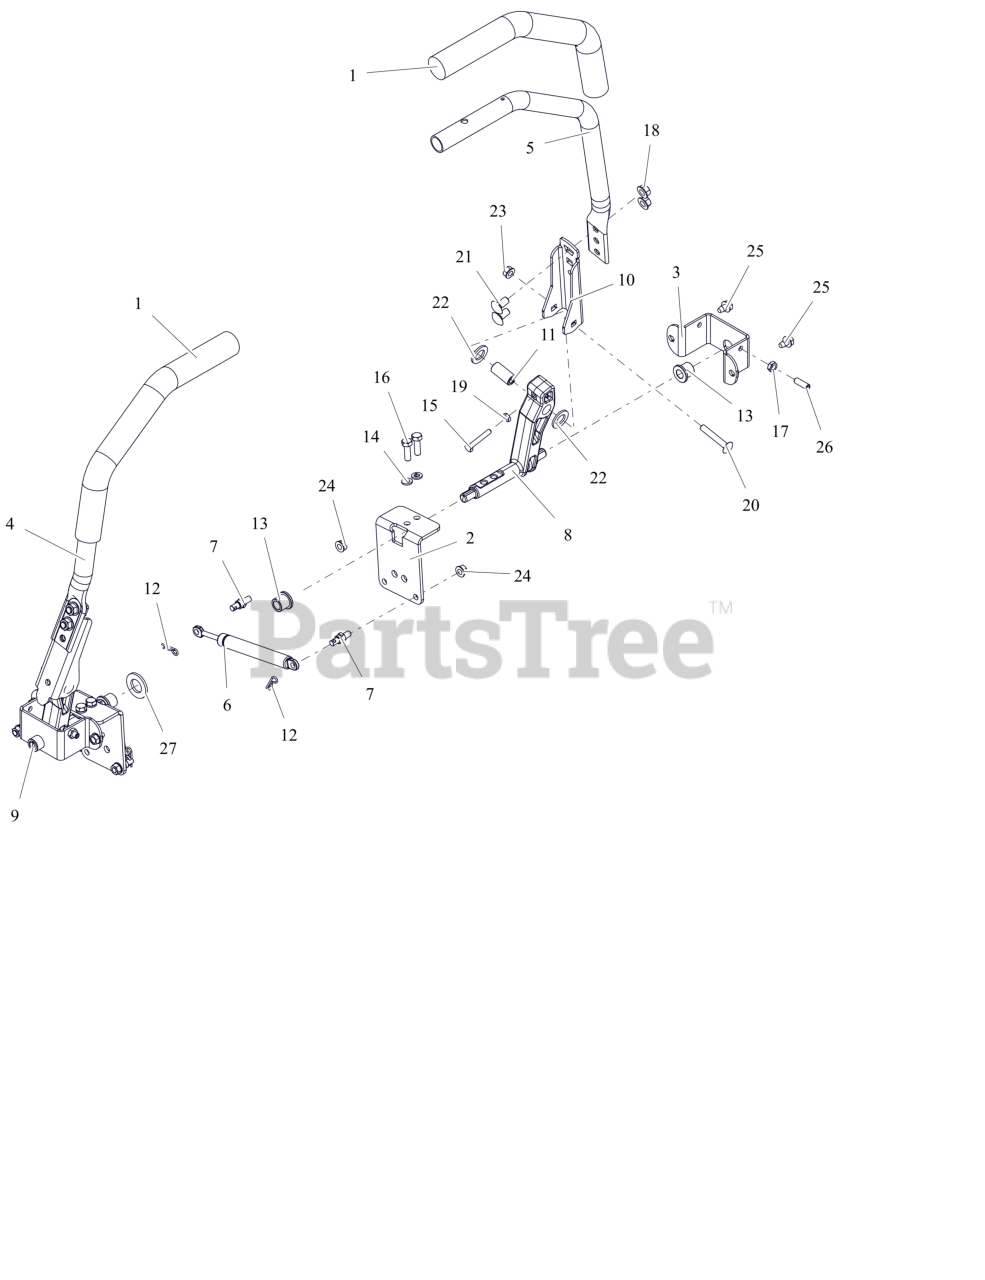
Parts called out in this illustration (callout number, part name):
1	GRIP, HANDLEBAR
2	BRKT, STEEERING
3	BRKT, STEERING
4	HANDLE- STEERING-RH
5	HANDLE- STEERING-LH
6	DAMPER, STRAIGHT MOUNT
7	COUPLER, DAMPER MOUNT
8	ARM- STEERING-LH LOWER (MACH)
9	ARM- STEERING-RH LOWER (MACH)
10	ARM- CONTROL UPPER
11	BSHG-SLV .342 X .627 X 1.331
12	PIN, HAIR #213 .08X1.19 ZCC
13	BHSG-FLG .500X.750X.750X.125
14	WSHR,LK-REG .312X.078 ZCC
15	BLT, HEX .25-20X1.50F G5 ZCC
16	BLT, HEX .31-18X1.00 G8 ZCC
17	NUT-JAM .312-18 G2 ZCC
18	NUT-LK-TOP-FLG .375-16 GG ZCC
19	NUT-JAM .250-20 G2 ZCC
20	BLT, RHSSN .31-18X2.00 G5 ZCC
21	BTL,RHSSN .375-16 X 0.75 G5 FPB
22	WSHR, FRICTION
23	NUT,LK-CTR-FLG .31-18 GF ZCC
24	NUT-LK-TOP-FLG .312-18 GF ZCC
25	SCR,TAP .312-18X.50 HWH TR ZCC
26	SCR-SET, .312-18X1.000
27	WSHR, FLT .812X1.469X.134 ZCC
